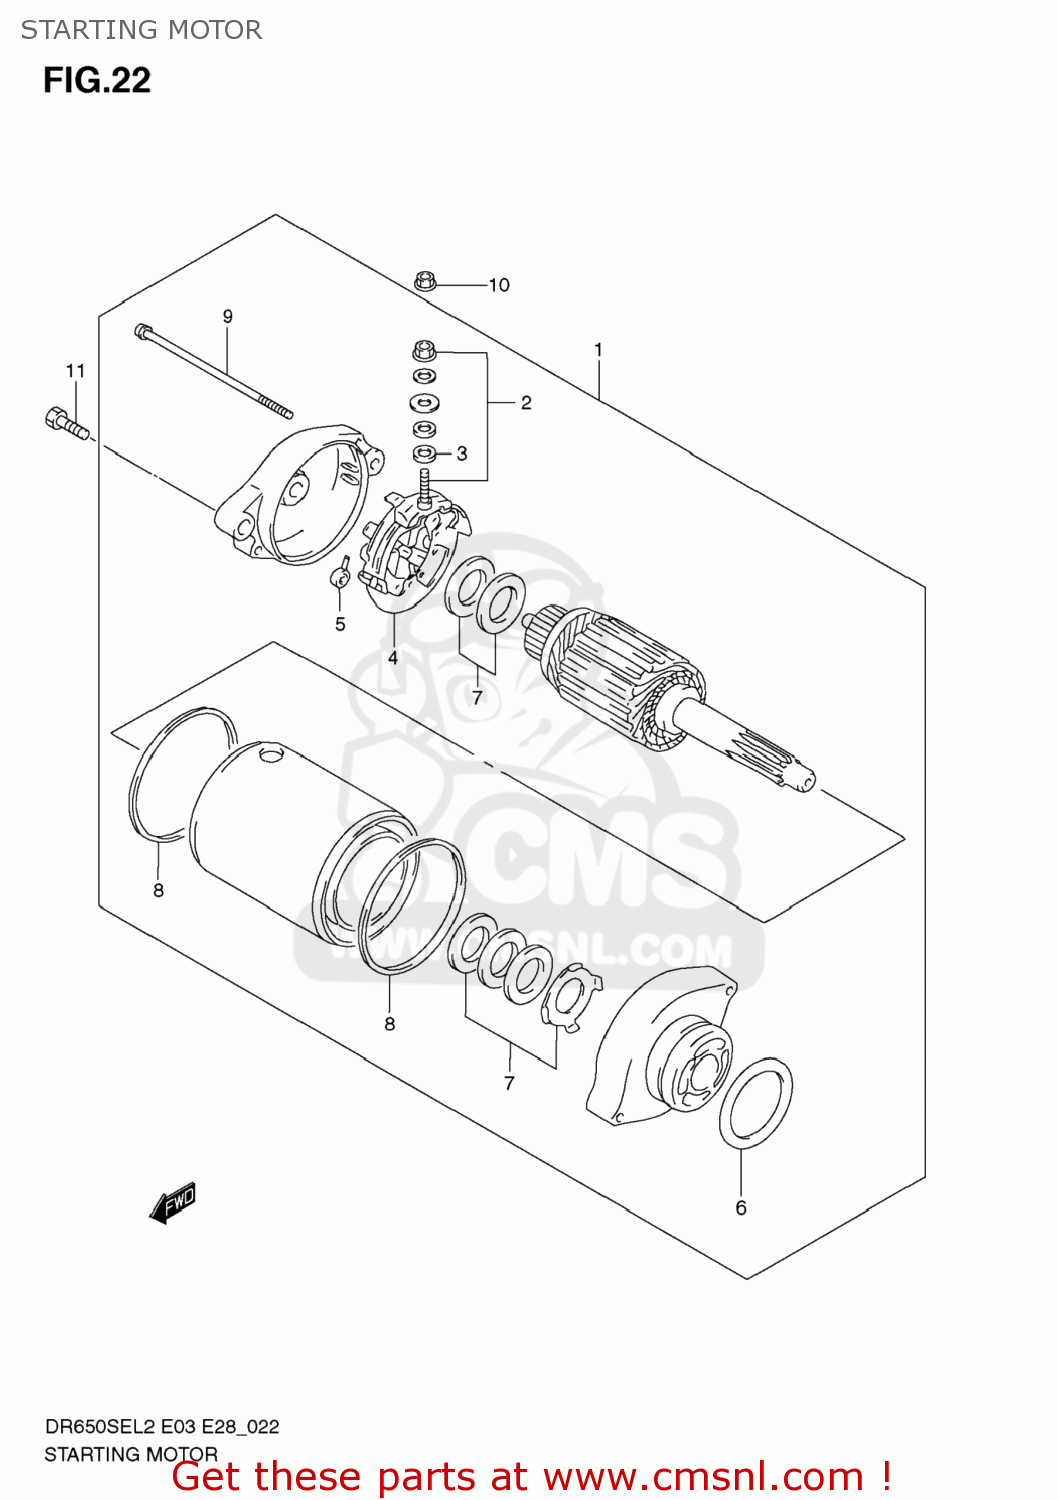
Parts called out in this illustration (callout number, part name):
1	MOTOR ASSY,STARTING
2	TERMINAL SET,BRUSH
3	O RING
4	HOLDER SET,BRUSH
5	SPRING,BRUSH
6	O RING
7	WASHER SET
8	O RING
9	BOLT
10	NUT
11	BOLT
